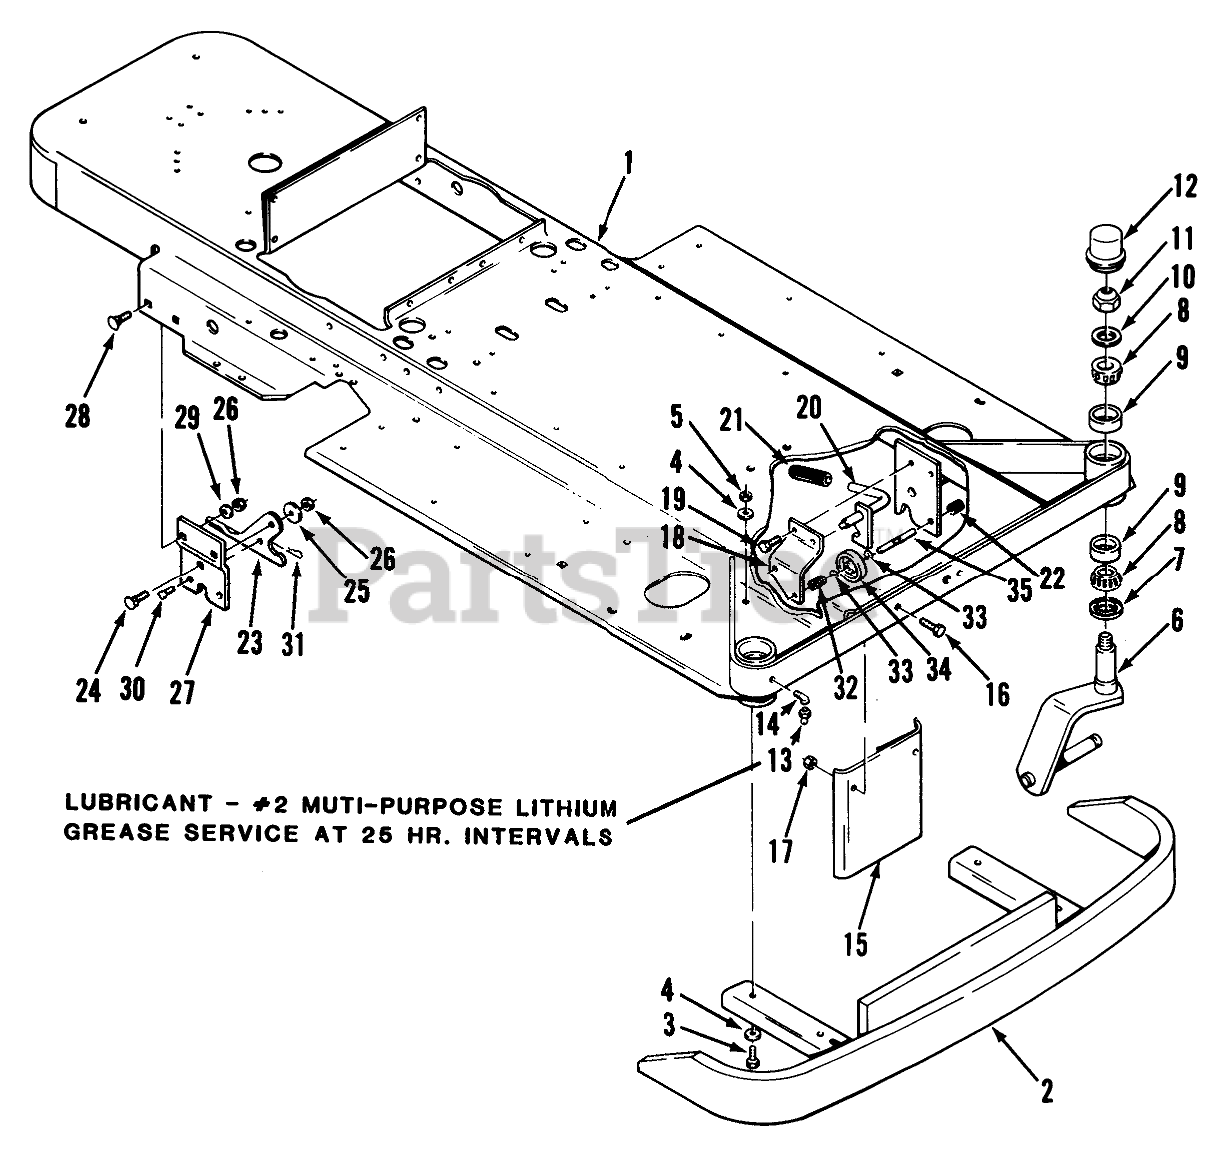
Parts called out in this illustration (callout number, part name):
1	Frame
2	Bumper-Front
3	BOLT
4	SAE Washer3/8
5	NUT
6	SPINDLE WELDMENT
7	Seal
8	Bearing
9	Cup
10	Washer
11	Nut
12	DUST CAP
13	Fitting-Grease
14	ELBOW 1/8 STREET
15	Shield
16	Bolt
17	Nut
18	Bracket RH
19	Screw
20	Latch RH
21	GRIP
22	CAP-ROD, PLUNGER
23	PLATE-LATCHING
24	Bolt
25	WASHER
26	NUT
27	Hitch Plate
28	Bolt
29	Washer
30	Pin
31	Hairpin
32	SPRING
33	RING-RETAINING
35	ROD-LOCK
